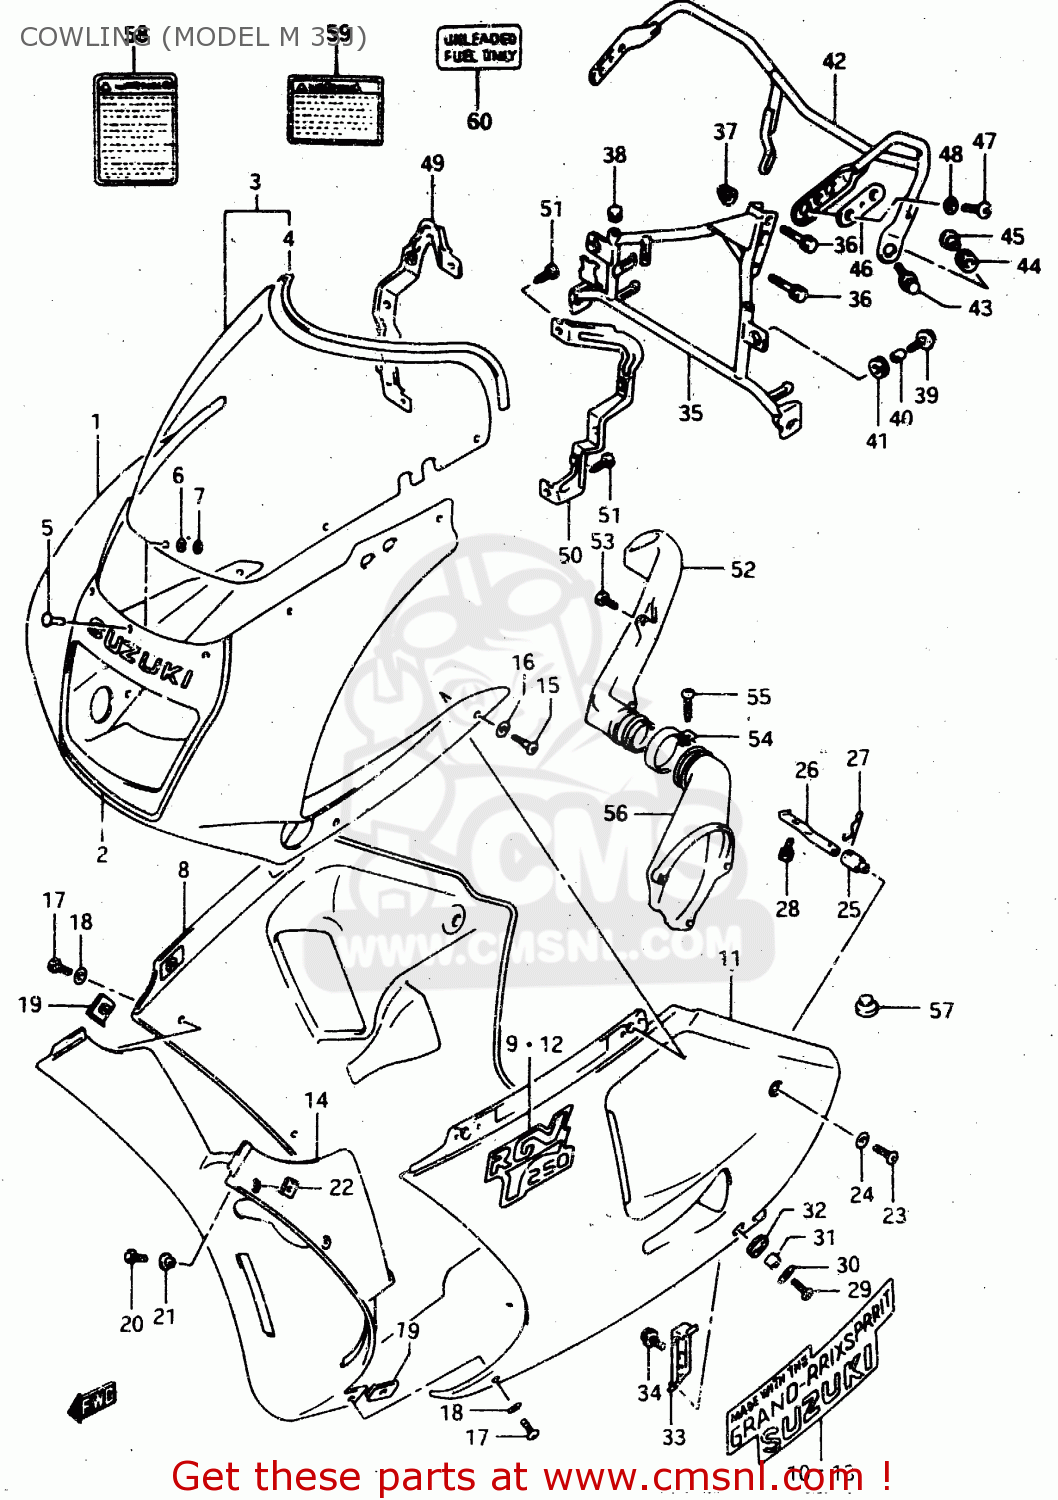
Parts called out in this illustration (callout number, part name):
1	COWLING ASSY, BODY (BLACK)
2	TAPE, UPPER
3	WINDOW SCREEN SET
4	MOLDING
5	PIN,WINDSCREEN
6	CUSHION
7	NUT
8	COWLING ASSY, UNDER RH (BLACK)
9	EMBLEM,UNDER,RGV
10	EMBLEM, UNDER RH
11	COWLING ASSY, UNDER LH (BLACK)
12	EMBLEM,UNDER,RGV
13	EMBLEM, UNDER LH
14	COWLING,UNDER CTR
15	SCREW(5X16)
16	WASHER(7X13X0.6)
17	SCREW(5X16)
18	WASHER(7X13X0.6)
19	NUT,RH & CTR UNDER COWLING
20	SCREW
21	WASHER(5.2X14X1.5)
22	NUT
23	SCREW(6X18)
24	WASHER
25	PLUG,UNDER COWL FTG,CTR
26	PIPE,UNDER COWL FTG CTR
27	PIN,UNDER COWLING FITTING PIPE
28	BOLT
29	SCREW(6X18)
30	WASHER(6.5X18X1)
31	SPACER (6.1X9X10)
32	CUSHION
33	BRACKET, UNDER LH
34	BOLT
35	BRACE,COWL
36	BOLT
37	NUT ,8MM
38	CAP(OD:12)
39	BOLT 6X20
40	SPACER (6.1X9X10)
41	CUSHION
42	BRACE, REAR VIEW MIRROR
43	BOLT 6X20
44	CUSHION
45	WASHER
46	CUSHION,RR VIEW MIRRORR
47	SCREW(6X12)
48	WASHER(6.2X19X1.5)
49	BRACKET,HEADLAMP FIT,R
50	BRACKET,HEADLAMP FIT,L
51	SCREW
52	BODY,AIR DUCT COWL NO.1
53	SCREW, FRONT & REAR
54	CLAMP
55	SCREW 4X25
56	BODY,AIR DUCT COWL NO.2
57	CUSHION
58	LABEL (WARNING SCREEN)
59	LABEL
60	LABEL,FUEL CAUTION
